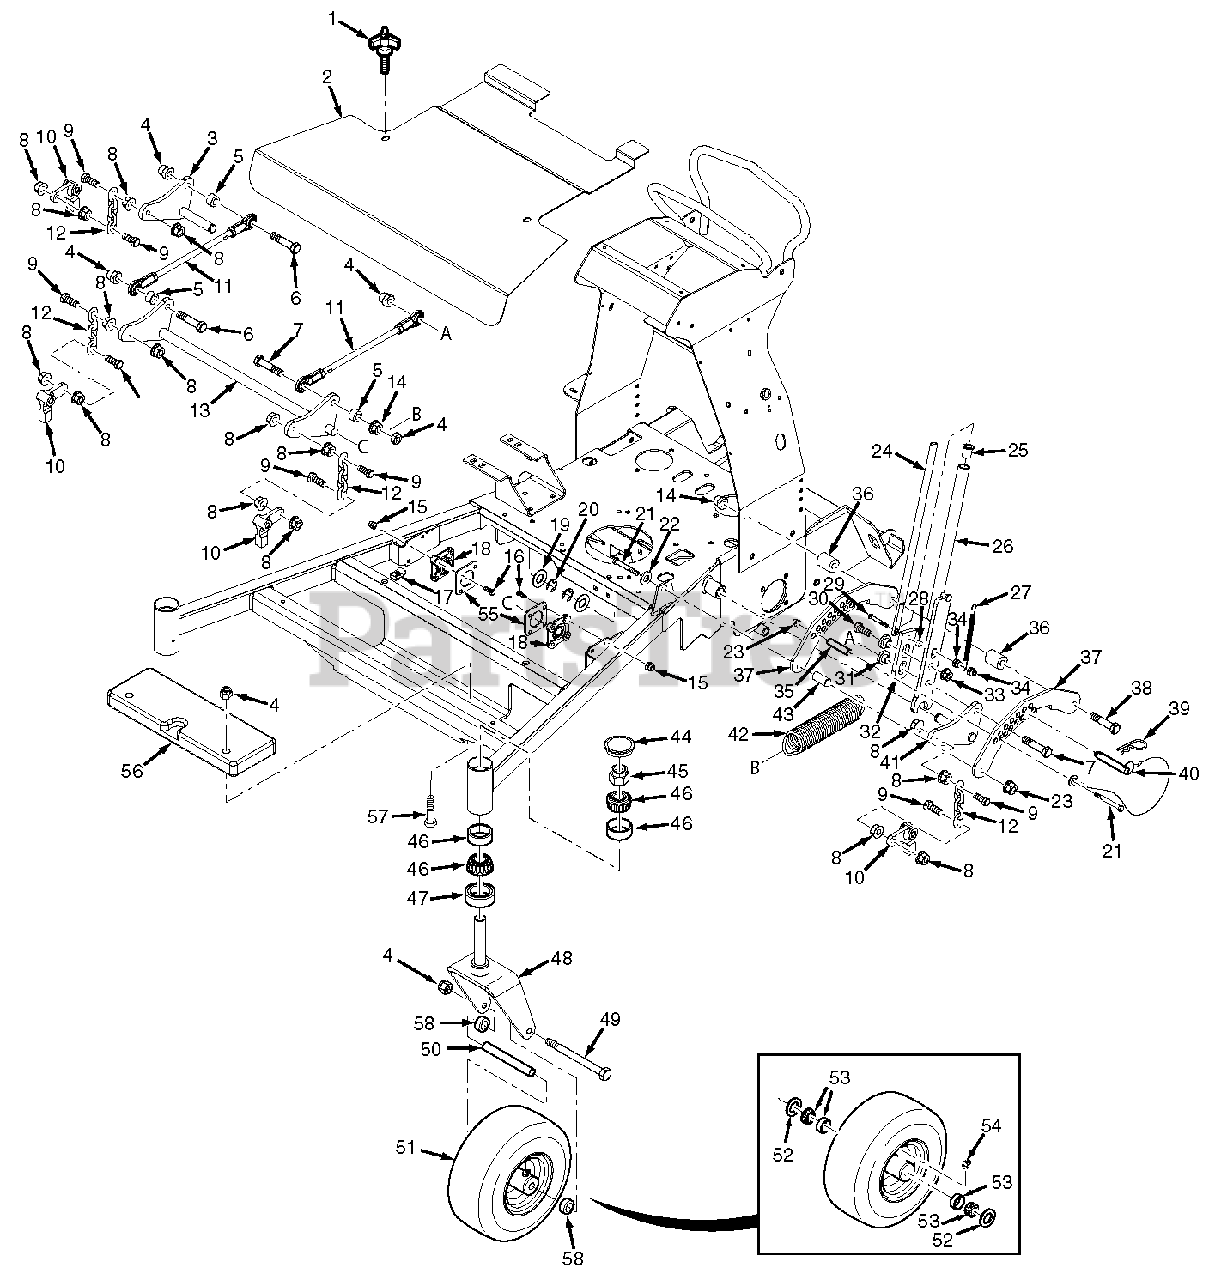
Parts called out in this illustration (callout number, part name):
1	Knob w/Stud
2	Belt Cover w/Decals (36A)
2	Belt Cover w/Decals (48V & 52V)
3	Arm Weldment, RH
4	Nut, Elastic Stop 1/2-13
5	Spacer
6	Bolt, Hex Head 1/2-13 x 2-1/2"
7	Bolt, Hex Head 1/2-13 x 3"
8	Nut, Serrated Flange 3/8-16
9	Bolt, Hex Head 3/8-16 x 1-1/2"
10	Lever, Deck Level
11	Linkage, Deck Lift (36A)
11	Linkage, Deck Lift (48V & 52V)
12	Chain
13	Deck Lift Weldment (36A)
13	Deck Lift Weldment (48V & 52V)
14	Nut, Serrated Flange 1/2-13
15	Nut, Elastic Stop 5/16-18
16	Bolt, Hex Head 5/16-18 x 1"
17	U-Nut, 3/8-16
18	Bearing, Deck Lift - 36A
18	Bearing, Deck Lift - 48V & 52V
19	Flatwasher, 3/4-.766 x 1.25 x .0598
20	Retaining Ring, .750 "E"
21	Bolt, Hex Head 3/8-16 x 3"
22	Flatwasher, 3/8-.391 x .938 x .105
23	Nut, Elastic Stop 3/8-16
24	Actuator Rod
25	Bearing
26	Handle Weldment, Deck Latch
27	Spring, Deck Latch
28	Spacer
29	Bolt, Hex Head 3/8-16 x 2-1/2"
30	Bolt, Hex Head 1/2-13 x 1-3/4"
31	Bushing, Deck Latch
32	Deck Latch, Outer
33	Nut, Serrated Flange 1/2-13
34	Nut, Elastic Stop 3/8-16
35	Spacer
36	Spacer (36)
36	Spacer (48 / 52)
37	Bracket, Deck Height
38	Bolt, Hex Head 1/2-13 x 4-1/2"
39	Hair Pin Cotter
40	Pin Assembly w/Lanyard
41	Arm Weldment, LH
42	Spring, Deck Lift
43	Spacer
44	Cap, Grease
45	Nut, Elastic Stop 1"-14
46	Bearing w/Race
47	Seal, 2" OD x 1.625 ID
48	Caster Yoke Weldment
49	Bolt, Hex Head 1/2-13 x 6-1/2"
50	Sleeve, Caster Wheel
51	Caster Wheel Assembly, 11 x 4.0-5
53	Bearing, Tapered Roller
54	Grease Fitting, 45 Degree
55	Reinforcement, Bearing - 48V & 52V
56	Weight
57	Bolt, Hex Head 1/2-13 x 2-3/4" (48V & 52V - One Weight)
57	Bolt, Hex Head 1/2-13 x 4-1/2" (36A - Two Weights)
57	Bolt, Hex Head 1/2-13 x 5-1/2" (Three Weights Installed)
58	Spacer, Caster Wheel
